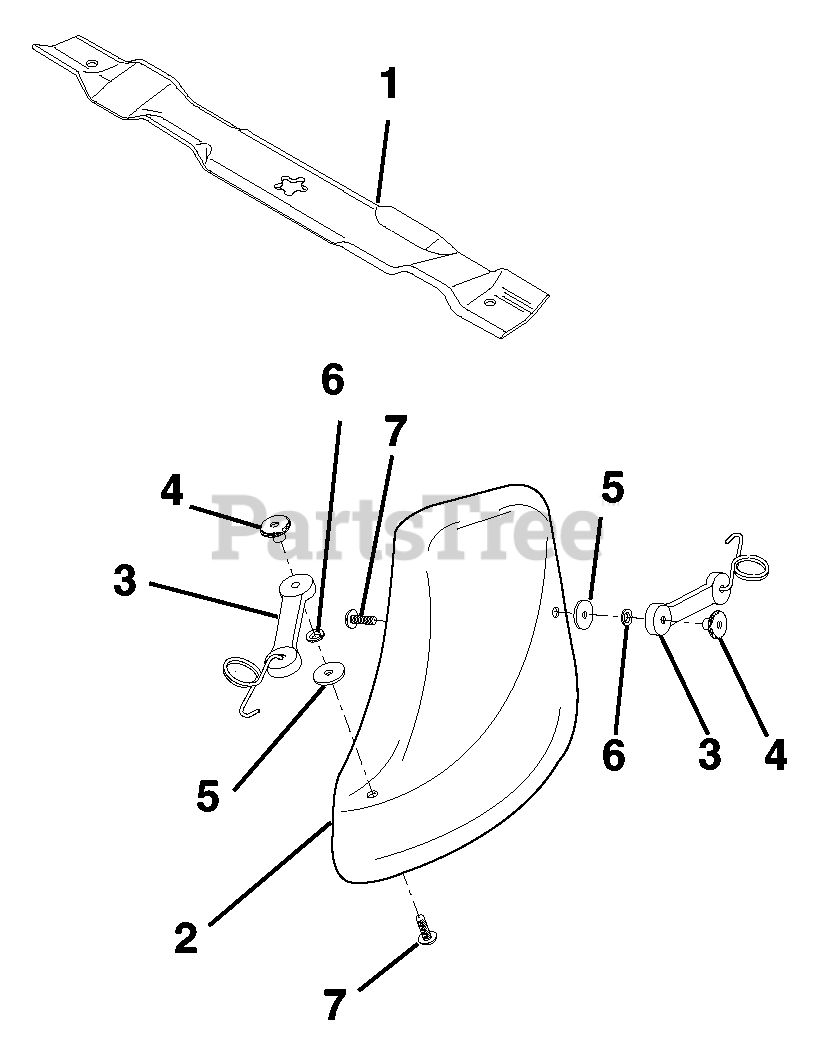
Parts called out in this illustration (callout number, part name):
1	Blade, Mulching
2	Mulcher Plate
3	Latch Hook
4	Nut, Weld
5	Washer #10
6	Washer, Lock#10
7	Screw
